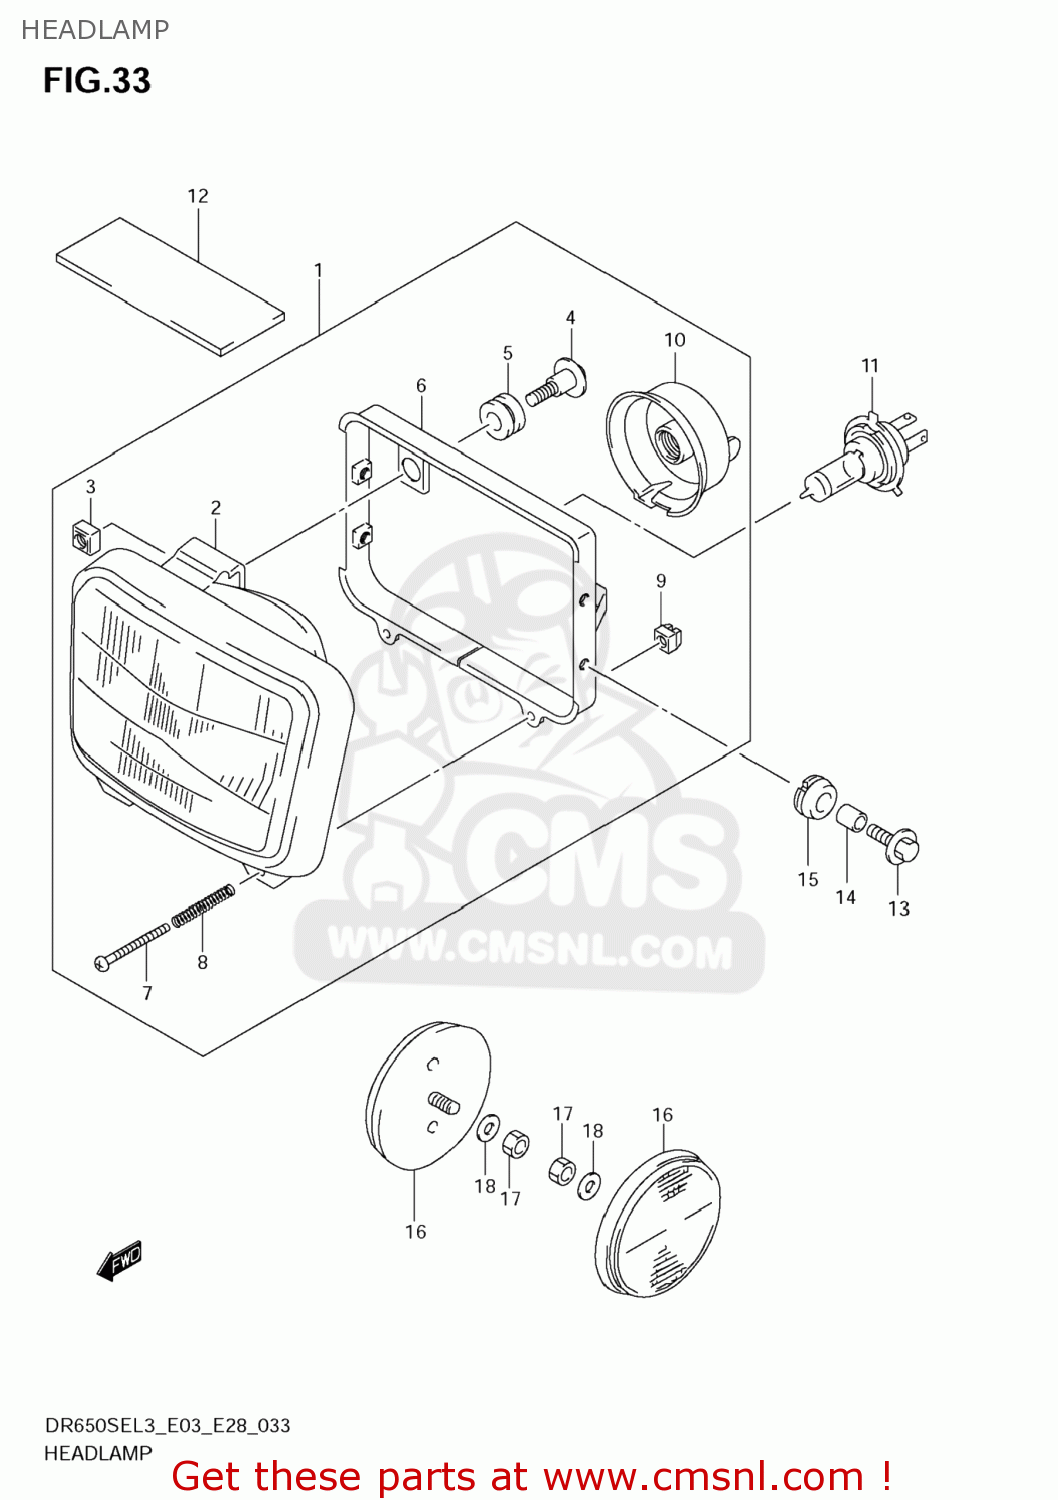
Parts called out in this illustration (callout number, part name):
1	HEADLAMP ASSY
2	UNIT ASSY
3	NUT
4	SCREW,MOUNTING
5	CUSHION
6	HOUSING
7	SCREW,ADJUSTING
8	SPRING,ADJUSTING
9	NUT,ADJUSTING
10	COVER,SOCKET
11	BULB(12V60/55W,H4)
12	PROTECTOR,WIRING HARNESS
13	BOLT(6X20)
14	SPACER(6.5X10X10)
15	CUSHION
16	REFLEX REFLECTOR ASSY,FR SIDE
17	NUT
18	WASHER,LOCK
